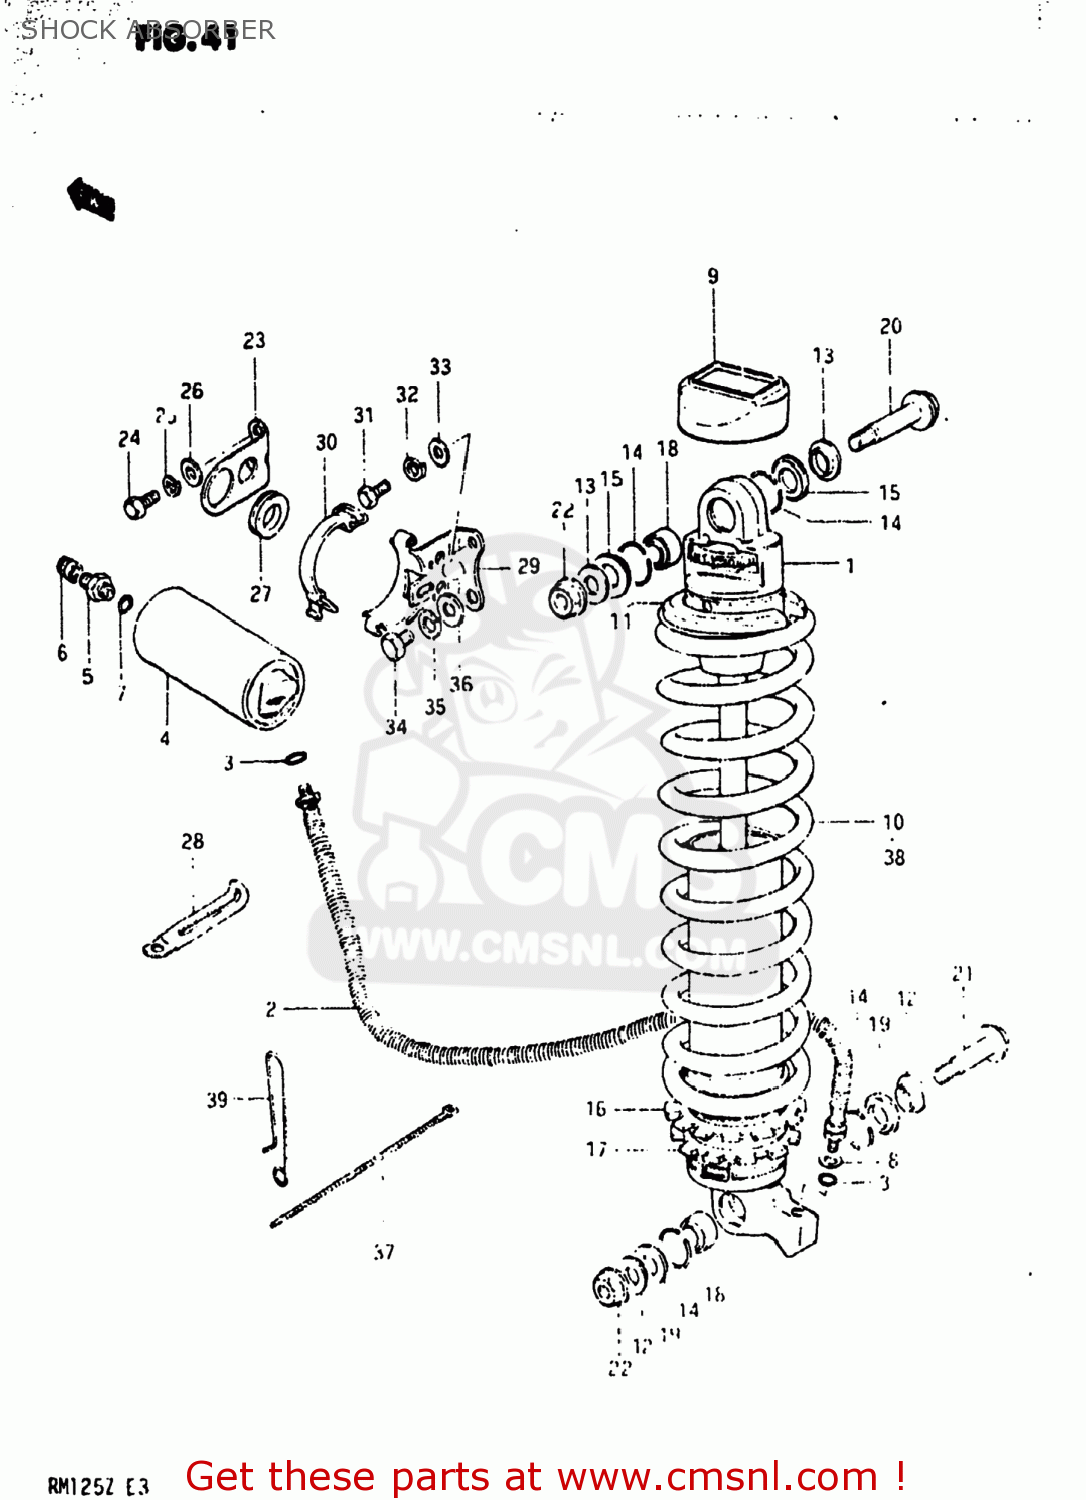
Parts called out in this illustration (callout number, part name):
1	ABSORBER ASSEMBLY,REAR SHOCK
2	HOSE,REAR SHOCK ABSORBER
3	O-RING,RESERVE TANK
4	RESERVE TANK,REAR SHOCK
5	VALVE ASSEMBLY,REAR CUSHION
6	CAP,VALVE AIR
7	O RING
8	WASHER,REAR SHOCK HOSE
9	CAP
10	SPRING
11	SPRING GUIDE
12	COLLAR
13	SPACER,REAR SHOCK,UPPER
14	RING
15	DUST SEAL,UPR
16	GUIDE,SPRING
17	GUIDE,REAR SHOCK ABSORBER SPRING
18	BEARING
19	DUST SEAL,LWR
20	BOLT
21	BOLT(10X54)
22	NUT
23	BRACKET,RESERVOIR TANK
24	BOLT
25	LOCK WASHER
26	WASHER
27	CUSHION,RESERVOIR TANK
28	CLAMP
29	BRACKET,RESERVOIR TANK
30	BAND
31	BOLT
32	LOCK WASHER
33	WASHER
34	BOLT
35	LOCK WASHER
36	WASHER
37	CLAMP
38	SPRING
39	GUIDE RES HOSE CLAMP
